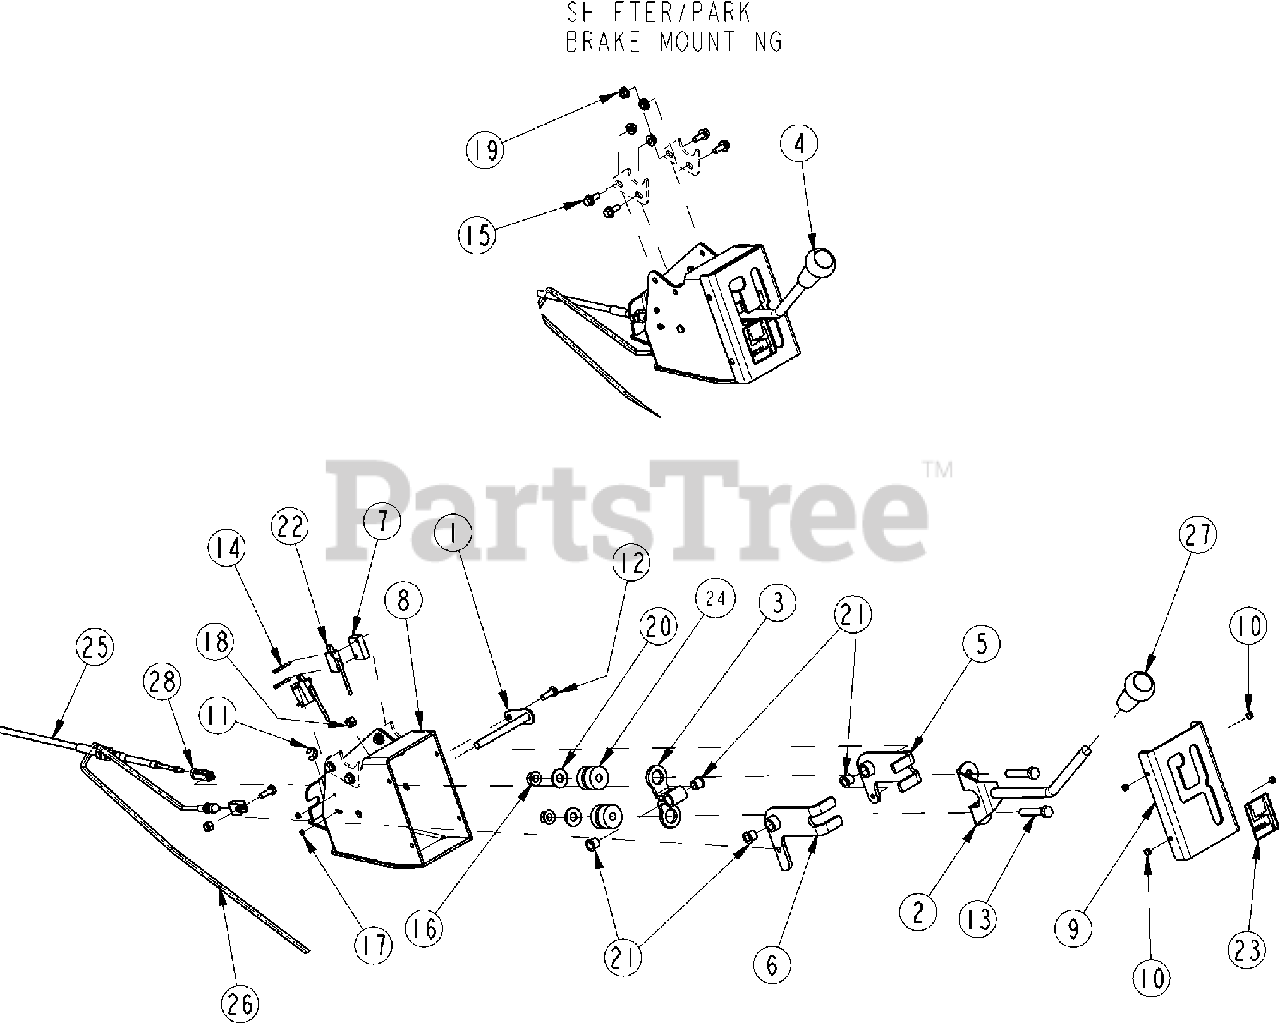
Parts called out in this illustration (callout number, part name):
1	PIN WELDMENT
2	SHIFT LEVER WLDMNT
3	SHIFT LEVER LOWER WLDMNT
4	SHIFTER ASSEMBLY
5	WELDMENT, F-N-R LEVER
6	WELDMENT, PARK BRAKE LEVER
7	SPACER PLATE
8	WELDMENT, SHIFTER HOUSING
9	PLATE, SHIFTER GATE
10	RIVET POP 3/16 .375 SSD66BS
11	E RETAINING RING EXTERNAL
12	HHCS 1/4-20X3/4 GR5
13	HHCS 3/8-16X2 GR5
14	HSHCS #4-40X1
15	HFS 1/4-20X5/8 GR5 ZNYCR
16	NUT FLANGE LOCK 3/8-16 PLT
17	NUT HEX #4-40 PLT
18	NUT HEX NYLOCK 1/4-20
19	NUT HEX FLG TL 1/4-20 ZNYCR
20	WASHER FLAT 3/8 USS PLT
21	BUSHING 1/2ODX3/8IDX1/2 FLG
22	PARK BRAKE MICRO-SWITCH
23	DASH SHIFTER DECAL
24	MOUNT MOTOR H SYTLE
25	SHIFT CABLE (DASH)
26	PARK BRAKE CABLE 105.00" LG
27	DASH SHIFTER KNOB
28	YOKE 10-32 W/ LOCK
